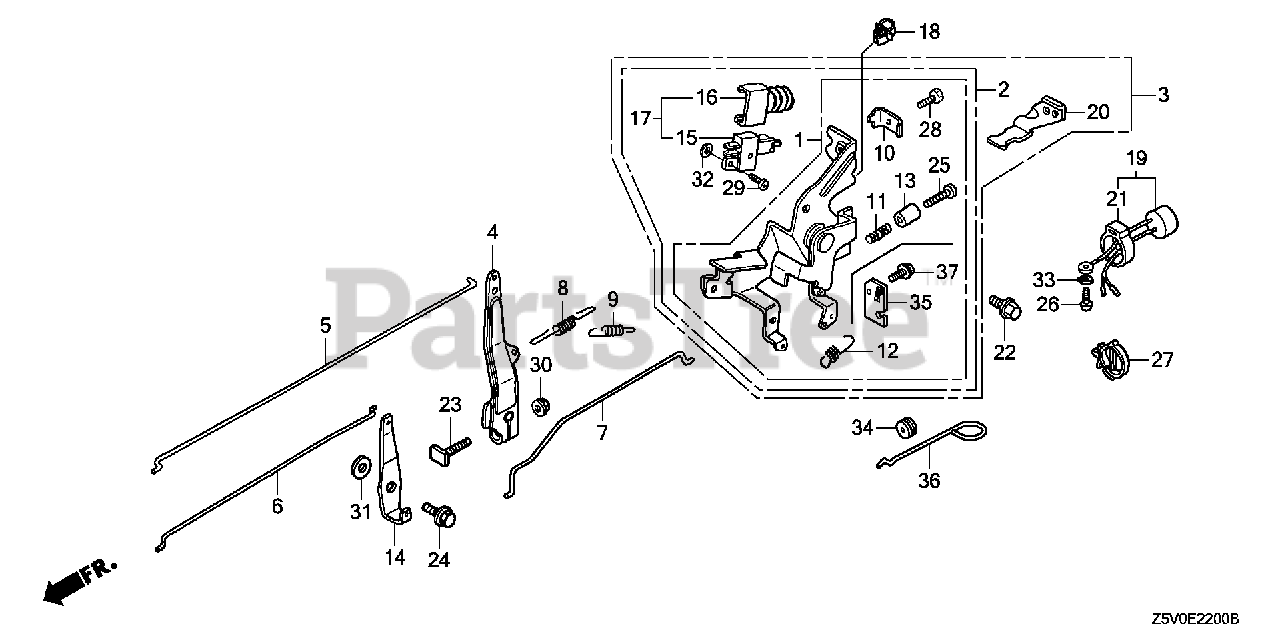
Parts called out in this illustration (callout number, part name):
3	CONTROL ASSY.
4	ARM, GOVERNOR
5	ROD, GOVERNOR
6	ROD, CHOKE
7	ROD, JOINT
8	SPRING, GOVERNOR
9	SPRING, GOVERNOR PRIMARY
10	HOLDER, CABLE
11	SPRING, CONTROL ADJUSTING Use from Engine SN 2327377.
14	LEVER, CHOKE JOINT
15	SWITCH ASSY., ENGINE
16	COVER, SWITCH
17	SWITCH ASSY., ENGINE STOP
19	BUZZER ASSY.
20	STAY, BUZZER
21	SUSPENSION, AUDIBLE PILOT
22	BOLT, FLANGE (6X12) (CT200)
23	BOLT, GOVERNOR ARM
24	BOLT, FLANGE (6MM)
25	SCREW, PAN (5X45)
26	SCREW, TAPPING (5X8)
27	CLIP, WIRE HARNESS
28	BOLT, RECESSED (5X16)
29	SCREW, PAN (4X14)
30	NUT, FLANGE (6MM)
31	WASHER, PLAIN (6MM)
32	WASHER, SPRING (4MM)
33	WASHER, SPRING (5MM)
34	GROMMET, CHOKE ROD
35	HOLDER, CABLE
36	ROD, CHOKE
37	BOLT, FLANGE (5X8)
